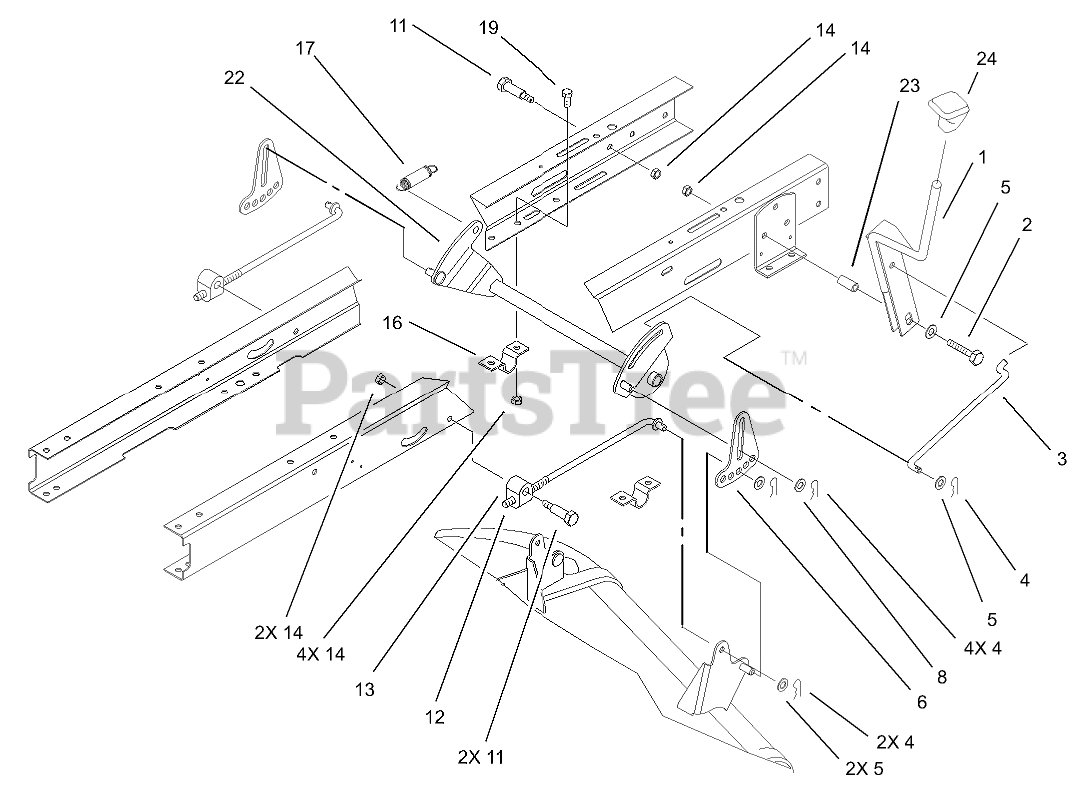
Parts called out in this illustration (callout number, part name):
1	HOC LEVER ASM
2	SCREW-HH
3	LINK-HOC
4	PIN-COTTER
5	WASHER-FLAT
6	LINK-ADJUSTING, HOC
8	WASHER-HARDENED
11	SCREW-SHOULDER, HH
12	ROD-HANGER, REAR
13	TRUNNION-HOC
14	NUT-LOCK, NI
16	CLAMP-PIVOT, HOC
17	SPRING-EXTENSION
19	SCREW-HH
22	PIVOT ASM
23	SPACER
24	KNOB-SHIFT
